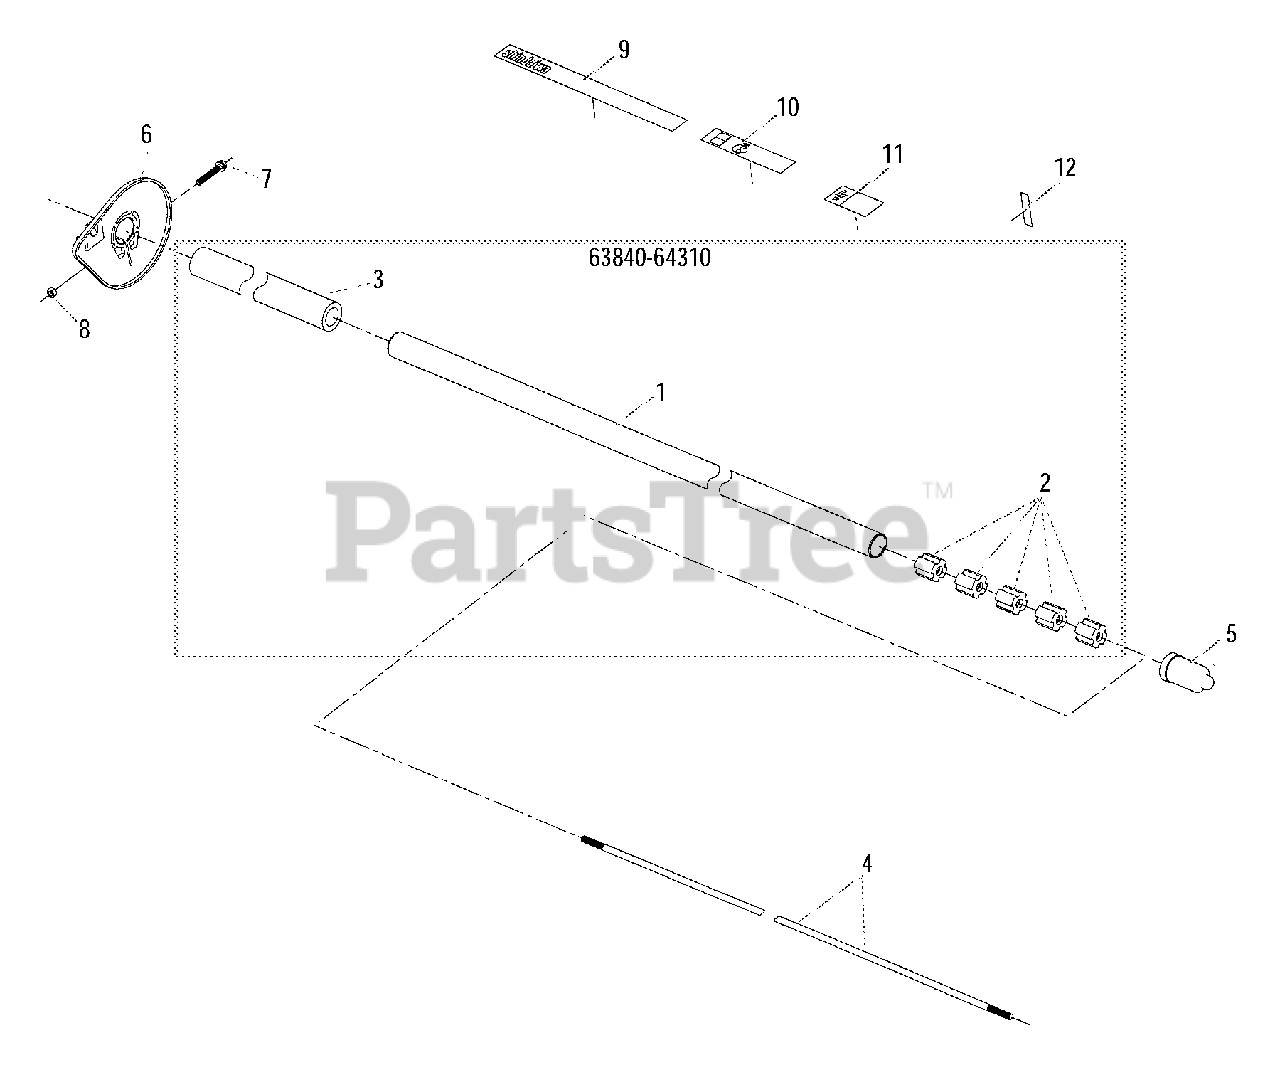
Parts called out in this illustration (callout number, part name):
1	MAIN PIPE ASSY
2	BUSHING
3	GRIP
4	PIPE, MAIN
5	CAP
6	PROTECTOR
7	SCREW - 5X30
9	LABEL - MODEL
10	LABEL - CAUTION
11	LABEL - CAUTION
12	LABEL - HANDLE LOCATION
63840-64310	MAIN PIPE ASSY
